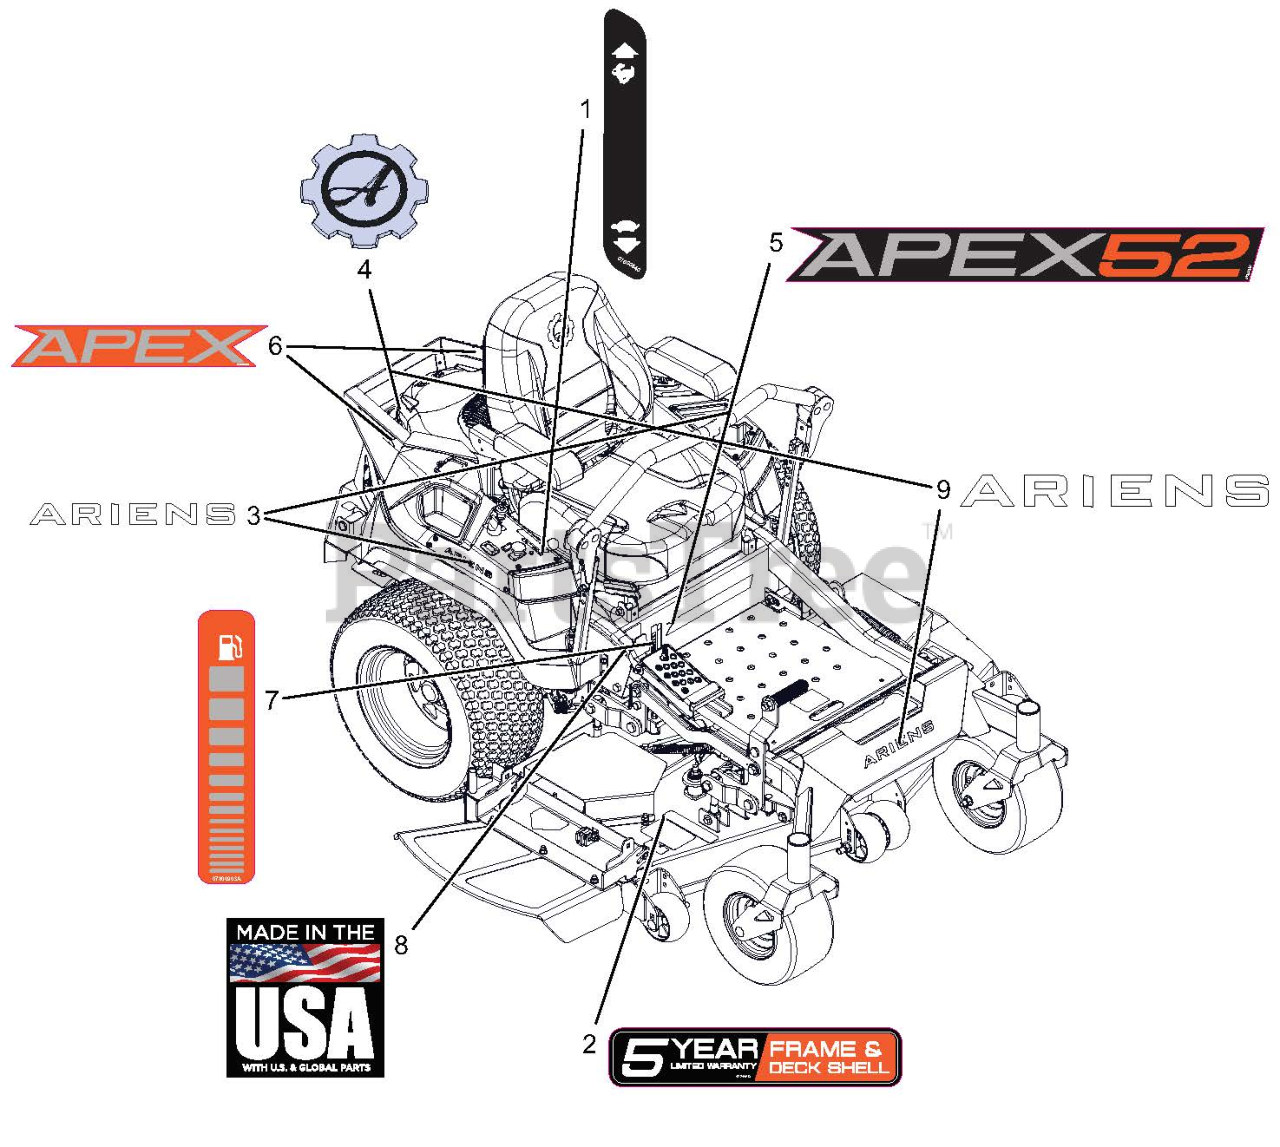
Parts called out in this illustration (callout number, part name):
1	DECAL, DASH DECAL
2	DECAL, DECK 5 YEAR-ARIENS
3	DECAL, ARIENS (6.50")
4	DECAL, ARIENS-GEAR BADGE -THK
5	DECAL, 52" APEX KICKPLATE
6	DECAL, APEX FENDER
7	DECAL, ARIENS FUEL LEVEL
8	DECAL, MADE IN USA
9	DECAL - ARIENS 9.625"
